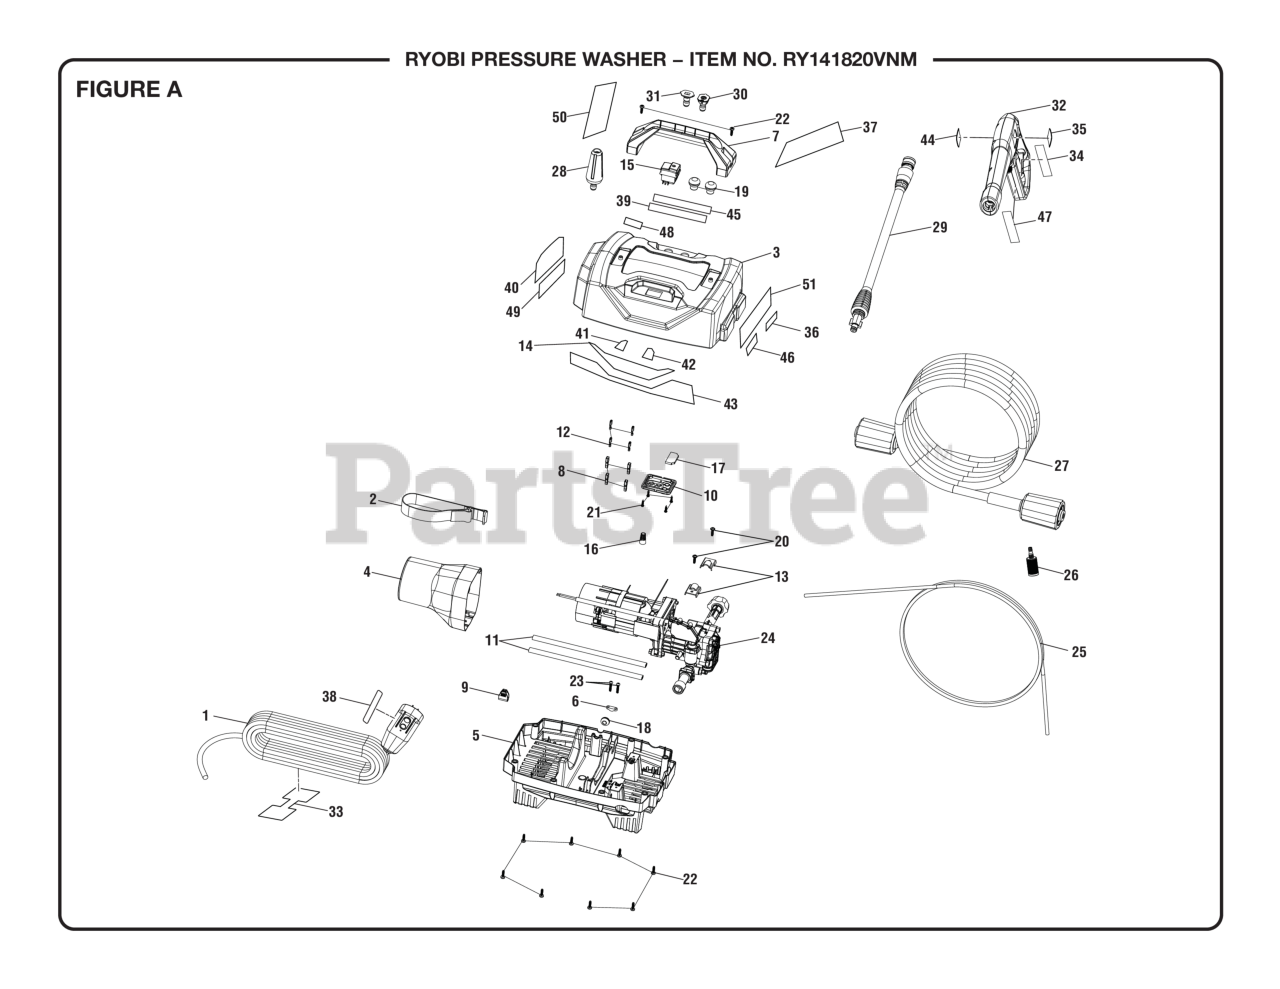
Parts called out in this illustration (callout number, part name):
1	Power Cord Assembly
2	Hose Storage Strap (Velcro)
3	Upper Housing
4	Air Shourd
5	Lower Housing
6	Cord Clamp
8	Plastic Sleeve (Terminal)
9	Electric Cord Clip
10	Switch Cover
11	Terminal Sleeve
12	Tinned Brass (Terminal)
13	Motor Clamp Plate
14	Logo Label
15	On/Off Switch
16	Tuerca para alambre
18	Housing Rubber Grommet
19	Nozzle Grommet
20	Screw w/ Washer (M4 x 16 mm, Round Hd.)
21	Screw (M2.9 x 14 mm, Pan Hd.)
22	Screw (M4.2 x 15 mm, Phillips Hd. S.T.)
23	Screw (M3.5 x 20 mm, Button Hd.)
24	Pump and Motor Assembly
25	Detergent Injection Tube
26	Detergent Injection Filter
27	High Pressure Hose
28	Turbo Nozzle
29	Spray Wand Assembly
30	Nozzle (15 deg)
31	Soap Nozzle (Blue)
32	Trigger Handle
33	Warning Label (Cord Wrap)
34	Trigger Handle Warning Label (French/Spanish)
35	Trigger Handle Warning Label (English)
36	LABEL, INSPECTED BY
37	Danger Hangtag (Spanish)
38	Power Cord Label
39	Quick Start Label
40	Regulatory Danger Label
41	Off Label
43	Performance Label
44	Trigger Handle Label (Logo Label)
45	Nozzle Selection Label
46	Soap Tube Attachment Label
47	Trigger Handle Data Label
48	Inquires Label (Ryobi)
49	Data Label
50	Nozzle Hangtag (PS141913)
51	Danger Icon Label (English/French)
